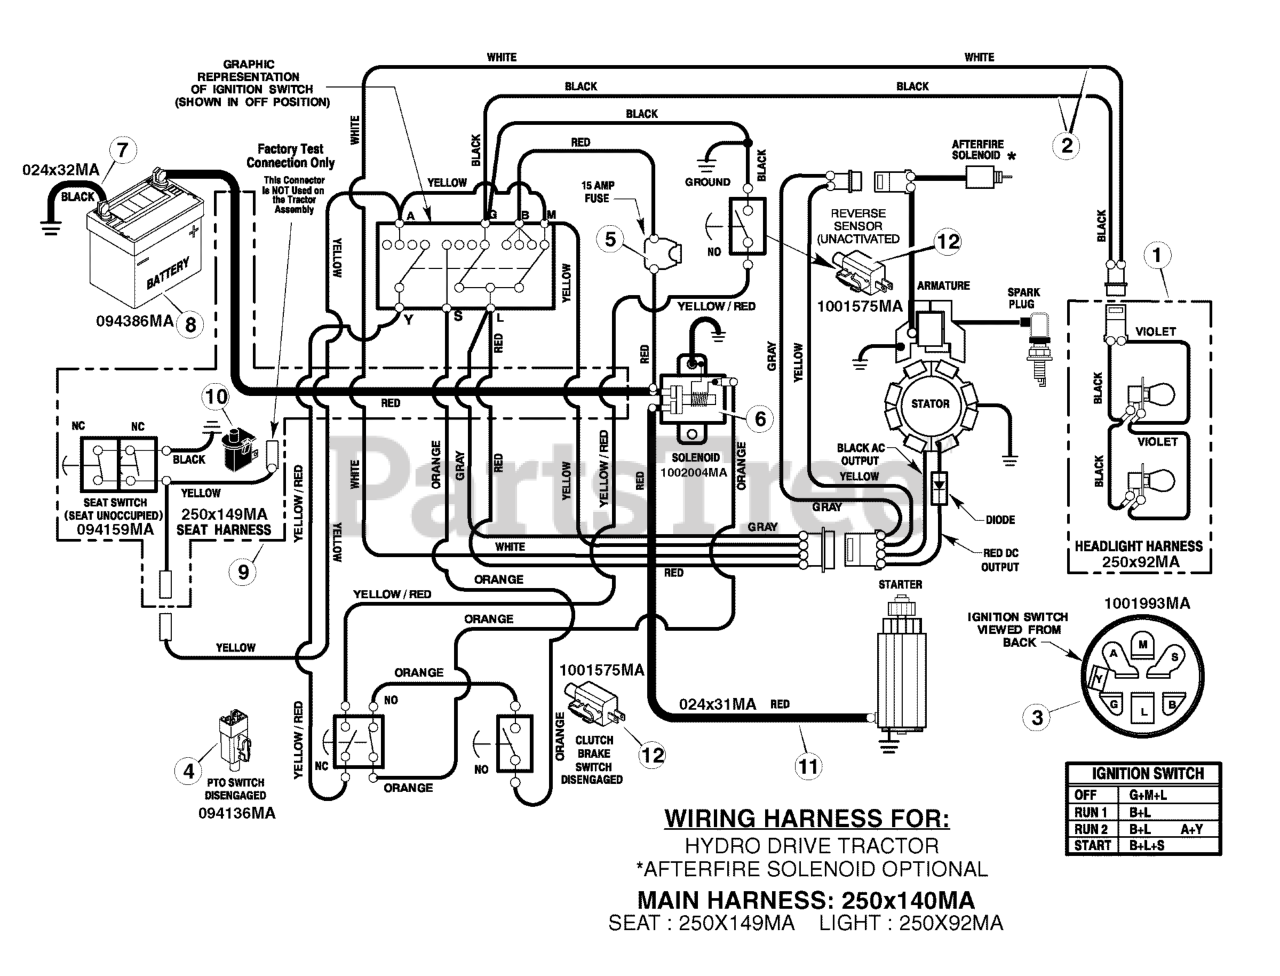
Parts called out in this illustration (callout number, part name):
1	Harness, Light Wire
2	Harness, Chassis Wire
3	Switch, Ignition
4	Switch, Limit
6	Solenoid
7	Cable, Battery Ground
8	Battery
9	Harness, Seat Switch Wire
10	Switch, Seat Sensor
12	Limit, Switch
